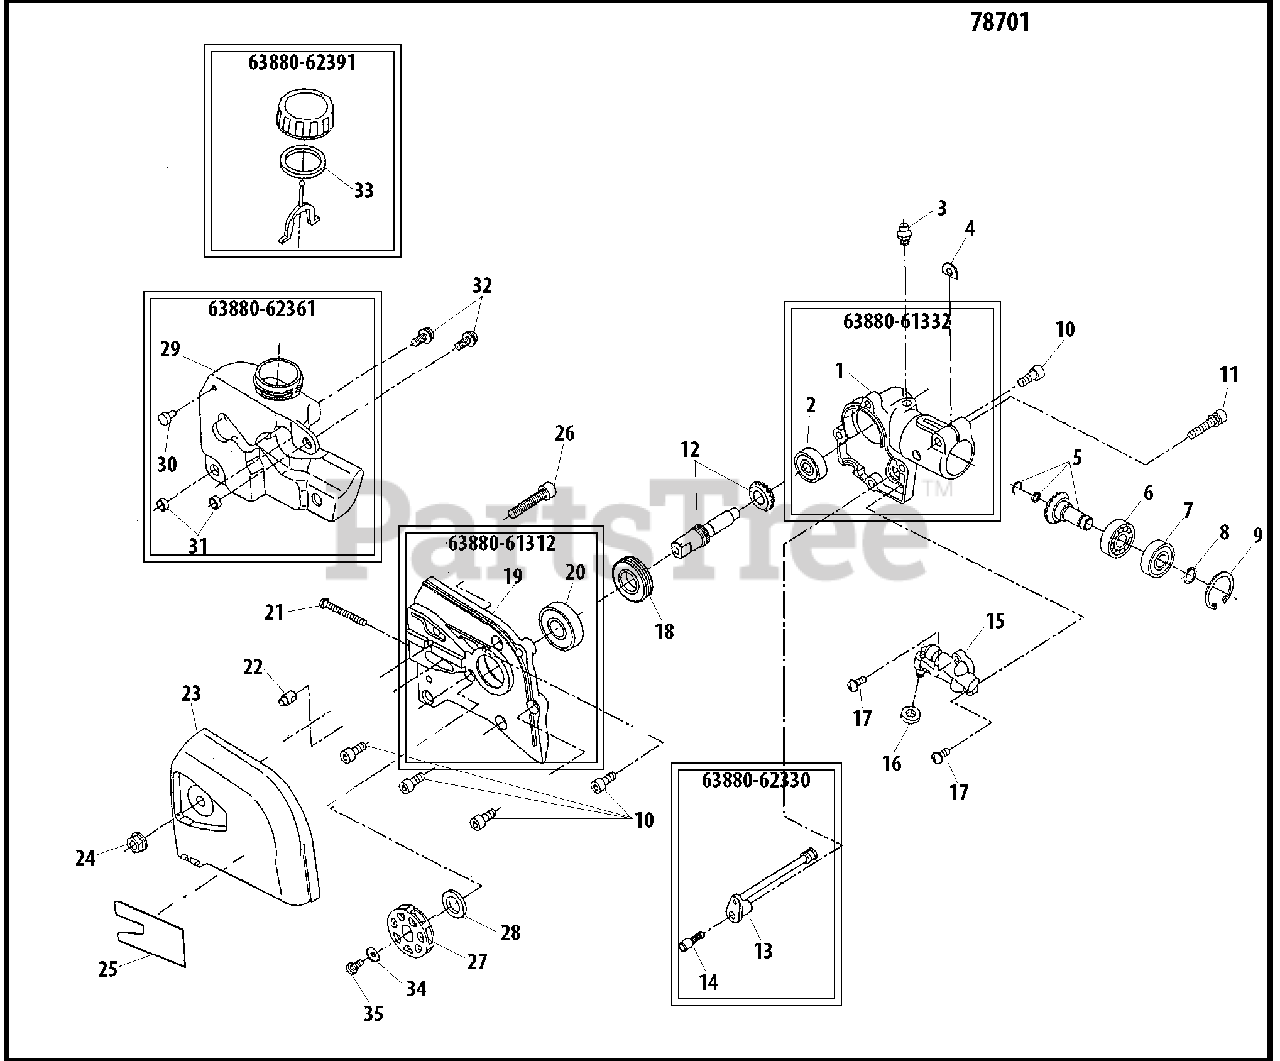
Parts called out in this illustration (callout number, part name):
1	CASE, GEAR - RIGHT
2	BEARING, BALL 627ZZ
3	FITTING, GREASE
4	D-WASHER
5	PINION, BEVEL
6	BEARING, BALL 609
7	BEARING, BALL 609ZZ
8	RING, SNAP
9	RING, SNAP Ø24
10	BOLT 5×12
11	BOLT M5×25
12	GEAR SET, BEVEL
13	PIPE, OIL
14	FILTER, OIL
15	OIL PUMP ASSY
16	GASKET, AUTO-OILER
17	SCREW
18	GEAR, WORM
19	GEAR CASE ASSY - LEFT
20	BEARING, BALL 6001 DDU
21	SCREW - 4×35
22	TENSIONER, CHAIN
23	COVER, SPROCKET
24	NUT, FLANGE M6
25	LABEL, CAUTION
26	BOLT 4×10
27	SPROCKET, DRIVE
28	COLLAR 12
29	TANK, OIL
30	VENT ASSY
32	SCREW M5×12
33	GASKET, CAP
34	WASHER M6
35	SCREW, BUTTON
